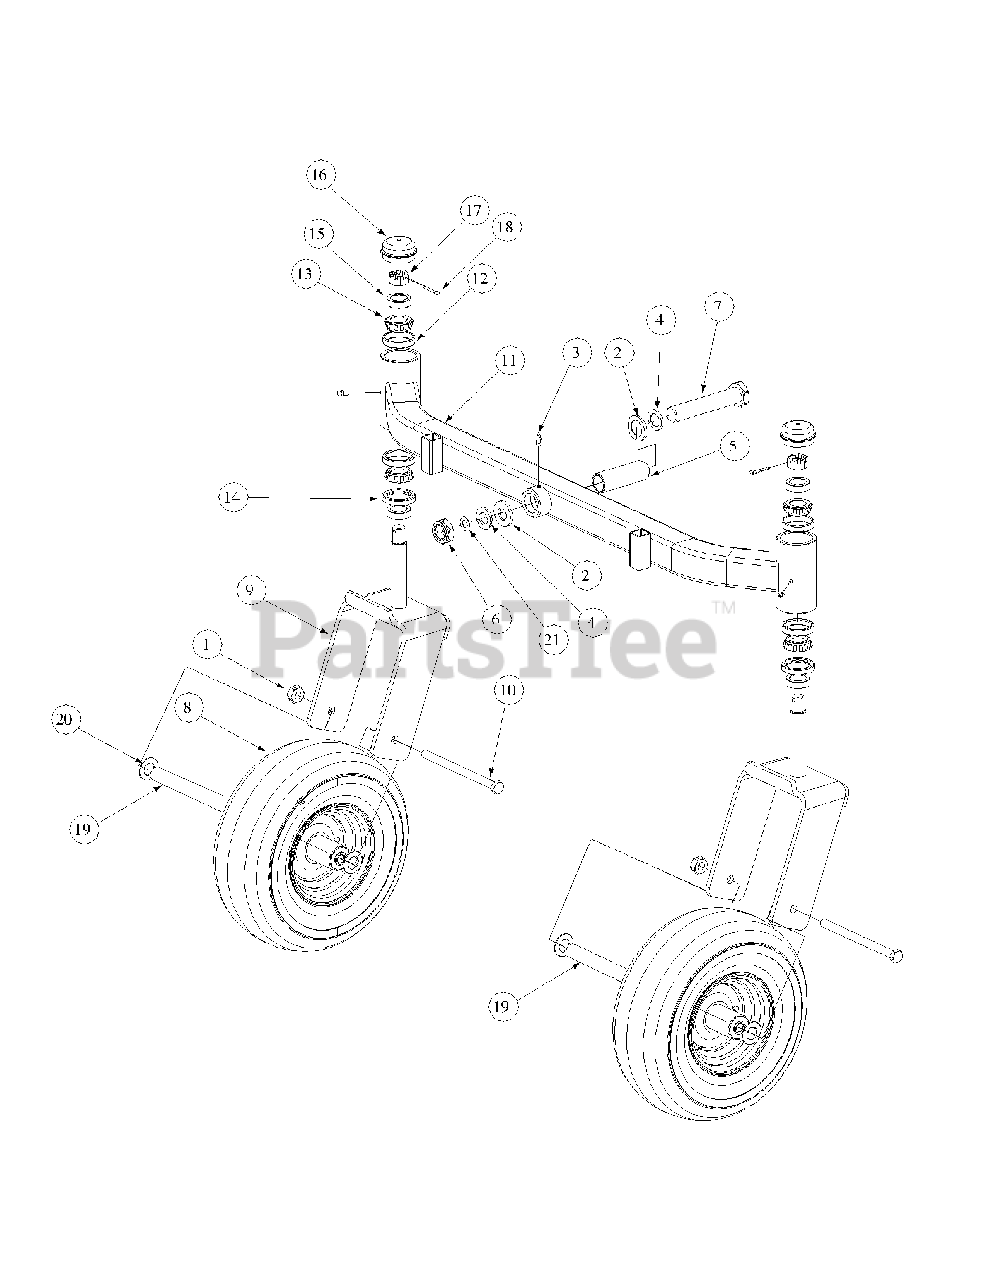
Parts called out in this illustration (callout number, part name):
1	Nut, 1/2-20, Center Lock
2	Bell Washer, 1.25 ID
3	Grease Fitting
4	Flat Washer, 1.00 ID
5	Spacer, 1.005 ID x 1.25 OD x 3.6
6	Nut, Jam, 1.0-14, Insert Lock
7	Hex Cap Screw, 1-14 x 5.0
8	Wheel Assembly, 13 x 6.50 x 6, White, includes:
9	Yoke, Caster Wheel
10	HHCS, 1/2-20, 7.50
11	Front Axle Assembly
12	Cup Bearing
13	Bearing Cone
14	Seal
15	Ring Seal
16	Grease Cap, 1.986 OD
17	Slotted Nut, 3/4-16
18	Cotter Pin, 5/32, 1.25
19	Wheel Spacer
20	Spacer, .812 ID x .218LG
21	Retainer Extension, Self Locking
